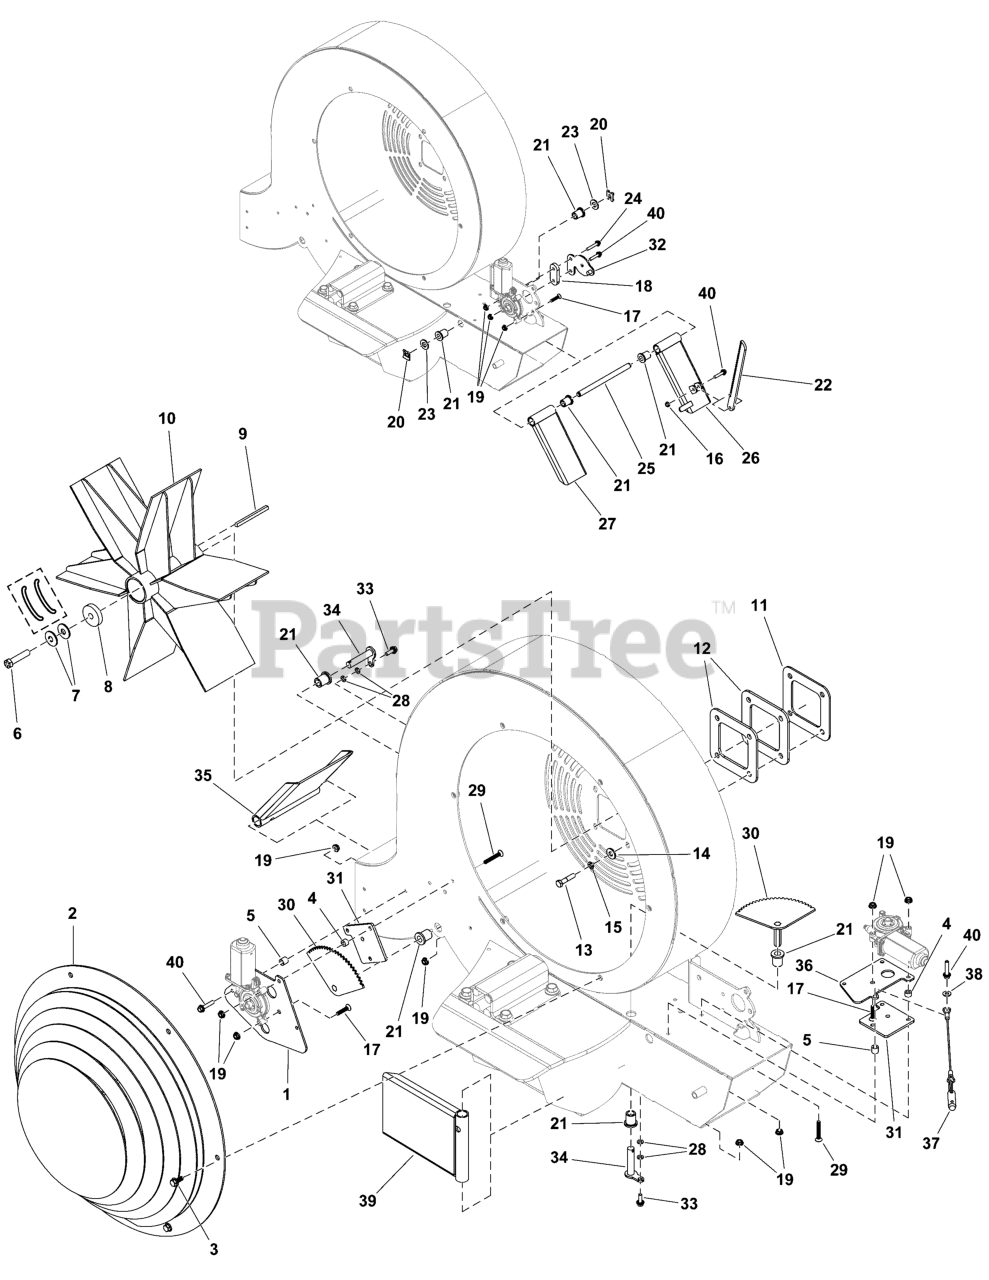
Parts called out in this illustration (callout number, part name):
1	PLATE, RIGHT DEFLECTOR COVER - BLK
2	WELD, SAFETY COVER X3 - BLK
3	SCREW, 5/16-18x0.750, GR5, WHIZ-LOCK, ZC
4	SPACER, .265 X .50 X .320, CZ
5	SPACER, .265 X .50 X .483, CZ
6	BOLT, 7/16-20 X 2
7	BELLEVILLE WASHER, 1.1875 X .442 X .098
8	WASHER, IMPLR, 1-3/4OD X 7/16ID
9	KEY, 1/4SQ X 3-3/8
10	WELD, IMPELLER, 19.00 OD
11	SPACER, MOTOR PLATE 10GA, CZ
12	SPACER, MOTOR PLATE 7GA. CZ
13	BOLT, 5/16-24 X 1-1/2, GD8, PHOS
14	WASHER, 5/16" USS
15	WASHER, 5/16 LOCK CZ
16	NUT, 1/4-20 HEX NYLON LOCK
17	SCREW, 1/4-20 X 1-1/4, ALLEN, SS
18	PLATE, RACK SPACER - BLK
19	NUT, 1/4-20 HEX SERR. FLANGE
20	CLIP, SAFETY
21	BUSHING, 1/2 X 3/4 X 1F
22	PLATE, DEFLECTOR RACK,CZ
23	WASHER, 1/2 SAE
24	BOLT, 1/4-20 X 1-1/2, FLANGE, CZ
25	ROD, DEFLECTOR SUPPORT 1/2 X 7.50
26	WELD, LEFT POWER DEFLECTOR, FB2000, CZ
27	WELD, LEFT SLAVE DEFLECTOR, FB2000,CZ
28	WASHER, 1/4 LOCK
29	SCREW, 1/4-20 X 1-3/4, ALLEN, SS
30	WELD, UNIVERSAL DEFLECTOR GEAR - BLK
31	PLATE, DEFLECTOR SPACER - BLK
32	WELD, RACK KEEPER, CZ
33	BOLT, 1/4-20 X 3/4, FLANGE, CZ
34	WELD, FORWARD DEFLECTOR PIN, CZ
35	WELD, RIGHT DEFLECTOR, X3, CZ
36	PLATE,FW DEFLECTOR MOTOR MNT - BLK
37	Z DEFLECTOR PIN RETAINING CABLE (Pin & Lanyard Assembly)
38	WASHER, 1/4 SAE
39	FORWARD DEFLECTOR X3, CZ
40	BOLT, 1/4-20 X 1-1/4, FLANGE, CZ
